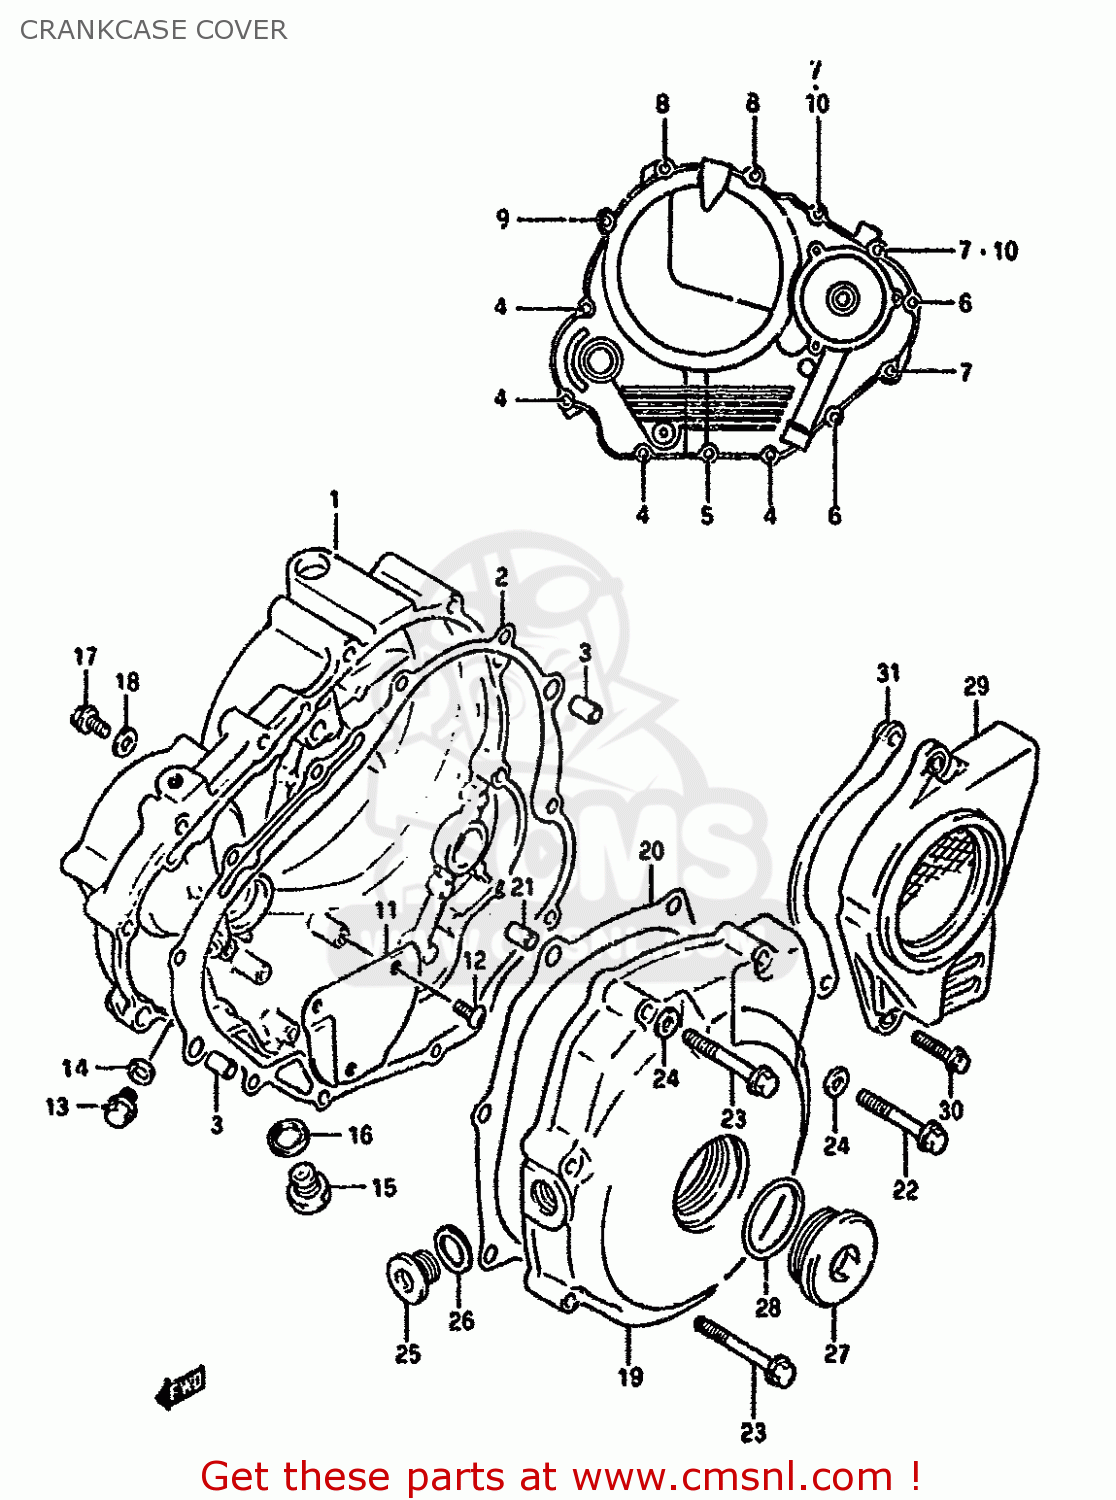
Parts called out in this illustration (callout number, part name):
1	COVER,CLUTCH
2	GASKET,CLUTCH COVER (NAS)
3	PIN
4	BOLT
5	BOLT
6	BOLT
7	BOLT
8	BOLT
9	BOLT
10	GASKET(5.8X13X1.2) (NAS)
11	SEPARATOR,OIL RETURN
12	SCREW
13	BOLT(6X8)
14	GASKET(6.2X11X1).2 (NAS)
15	PLUG,14X12
16	GASKET(14X19.2X2) (NAS)
17	SCREW (6X10)
18	GASKET(5.8X13X1.2) (NAS)
19	COVER,MAGNETO
20	GASKET,MAGNETO COVER (NAS)
21	PIN
22	BOLT
23	BOLT
24	GASKET(5.8X13X1.2) (NAS)
25	PLUG,14X12
26	GASKET(13.8X18.8X4.8) (NAS)
27	PLUG(SILVER)
28	O RING(D:3.1,ID:32.7)
29	COVER,ENGINE SPROCKET
30	BOLT
31	PLATE,FR CHAIN GUIDE
